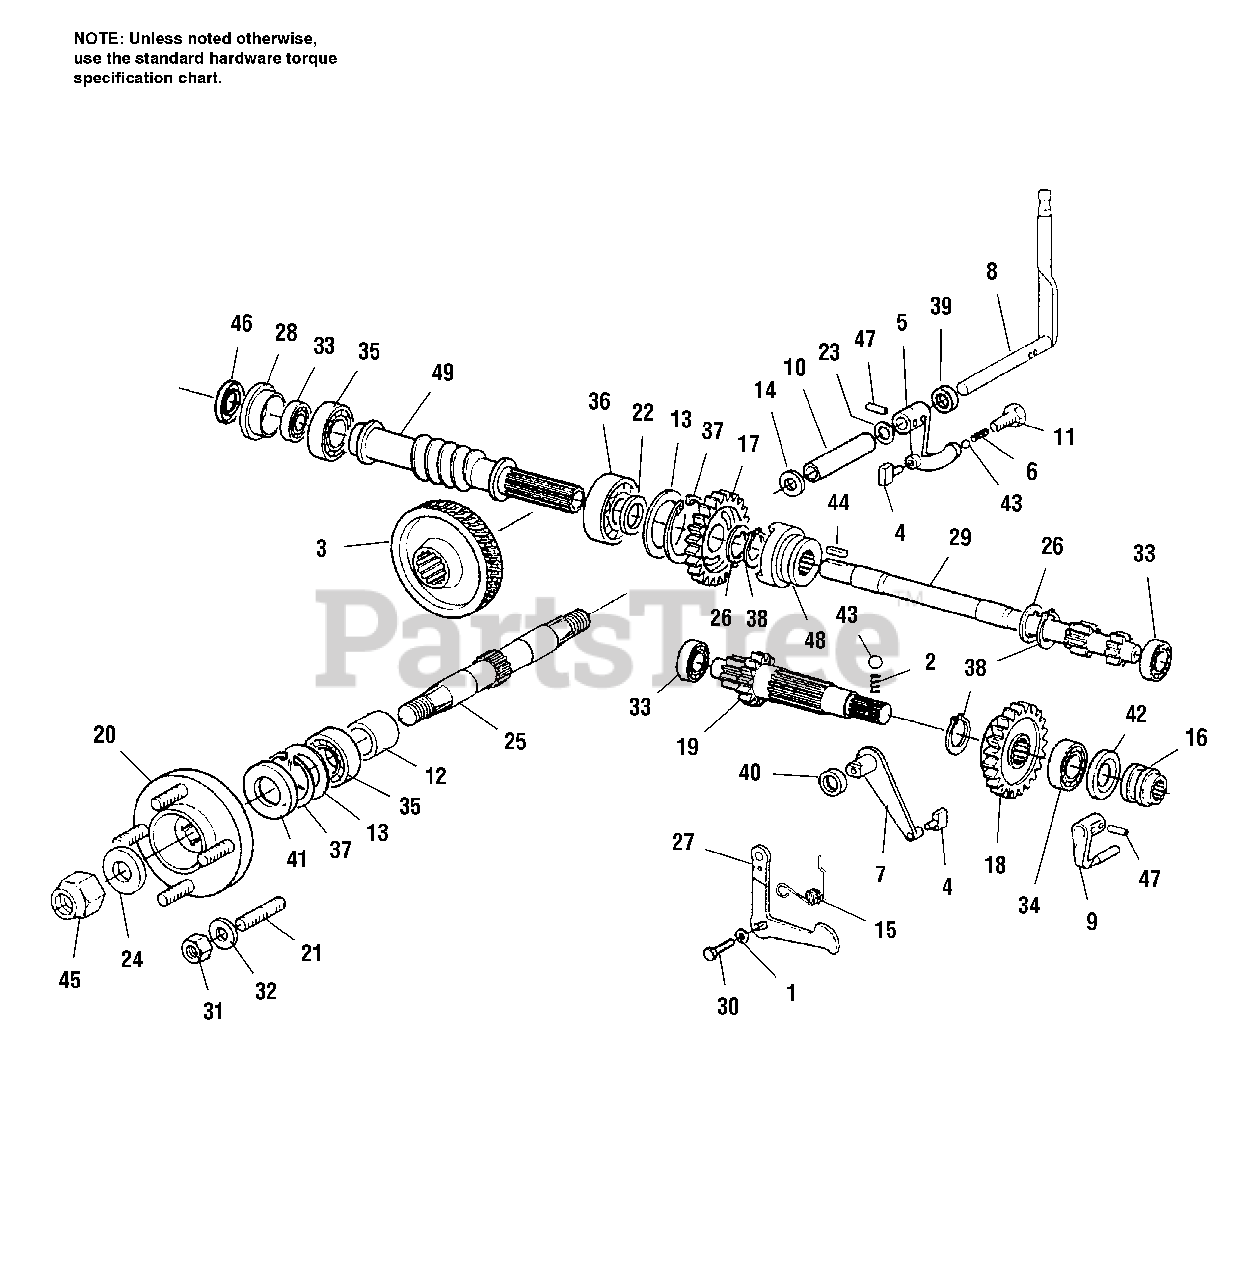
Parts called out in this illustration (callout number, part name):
2	SPRING-Compression, 1/4"
3	GEAR-Wheel, Brass
5	ARM-N/1/2, Engage
6	SPRING-Compression, 10mm
7	SHIFT ARM-Forward/Reverse Pivot
8	ROD-Gear Shift
9	ARM-PTO Engage
10	SPACER-Sleeve
13	SHIM, 52mm x 42mm x 0, 3, 4, 5
14	SHIM, 20mm x 12mm x 1.50mm
15	SPRING, Directional Control
16	SPLINE HUB-PTO
18	GEAR-Reverse
19	SHAFT-Reverse Pinion & PTO
23	WASHER, 20mm x 12mm x .03 - .05mm
25	SHAFT-Wheel Axle
26	WASHER-Keyed
27	ARM-Forward/Reverse Shift
29	SHAFT-PTO Engage
30	BOLT-Hex Hd, 6mm x 14mm
31	NUT, 12mm x 1.25mm
32	WASHER,12mm
33	BEARING-PTO Shaft, 15mm x 35mm x 11mm
34	BEARING-PTO Shaft, 20mm x 47mm x 14mm
35	BEARING-Wheel & Worm Shaft
36	BEARING-Worm Wheel Drive Shaft
37	SNAP RING, 52 I
38	SNAP RING, 24 E
39	SEAL-N/1/2 Arm, 12mm x 19mm x 5mm
40	SEAL-F/R, 16mm x 24mm x 4mm
41	SEAL-Tine Axle, (Wheel Shaft), 25mm x 52mm x 8mm
42	SEAL-PTO, 20mm x 35mm x 7mm
43	BALL-Steel, 1/4"
45	NUT, 20mm x 1.50mm
47	PIN-Roll, 5mm x 20mm
48	PINION-Input
49	SHAFT-Worm Wheel Drive
